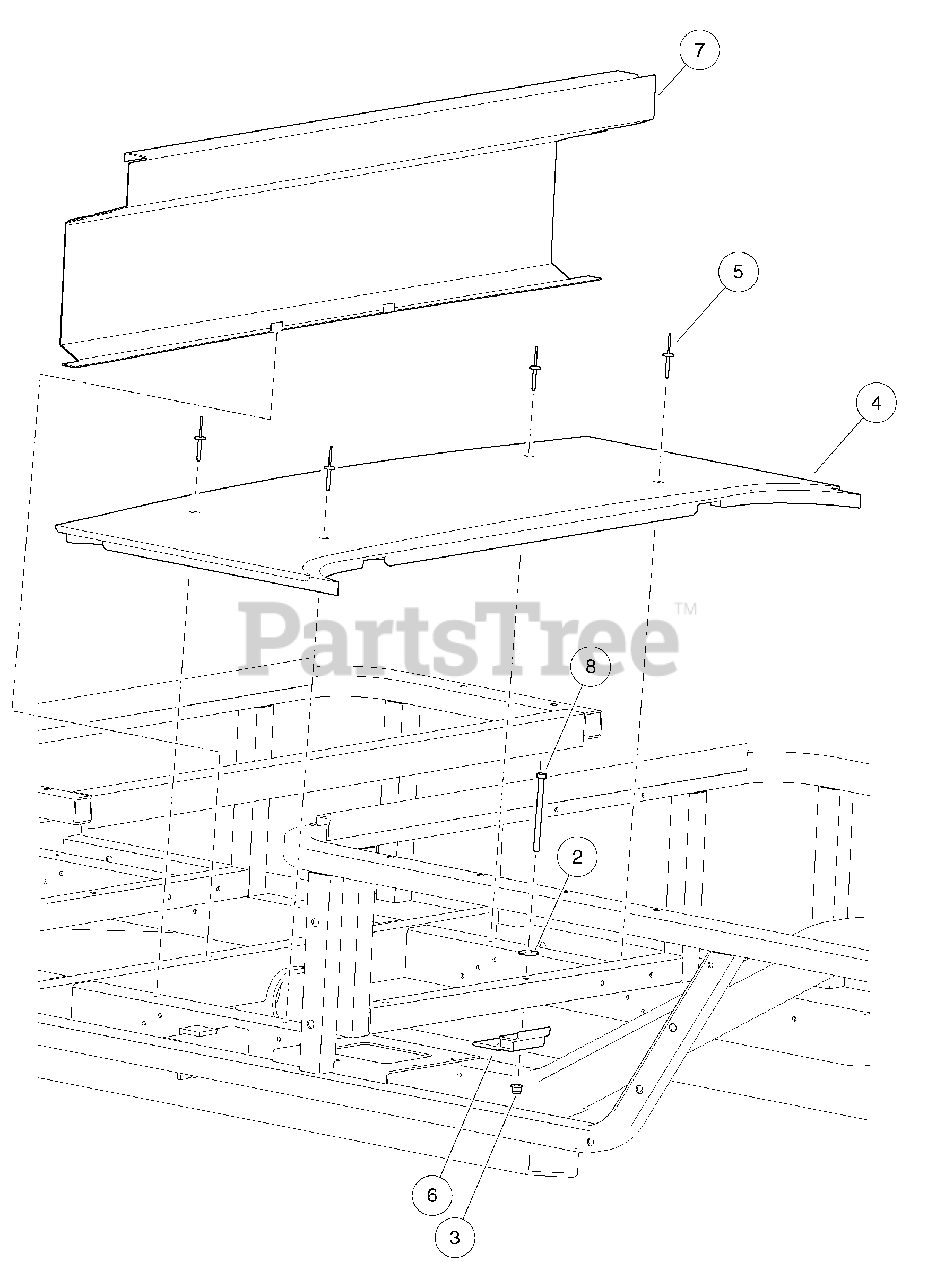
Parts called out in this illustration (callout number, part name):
1	Instl, Floorboard, Rear
2	Washer, 5/16 Type B Flat
3	Lock Nut, Flg M8 X 1.25 Nylon
4	Floorboard, Lower
5	3/16 X 1.19 Alum Rivet, Blk
6	Bracket, Support, Floorboard
7	Plate, Footwell, Rear
8	Bolt, M8 X 1.25 X 110
